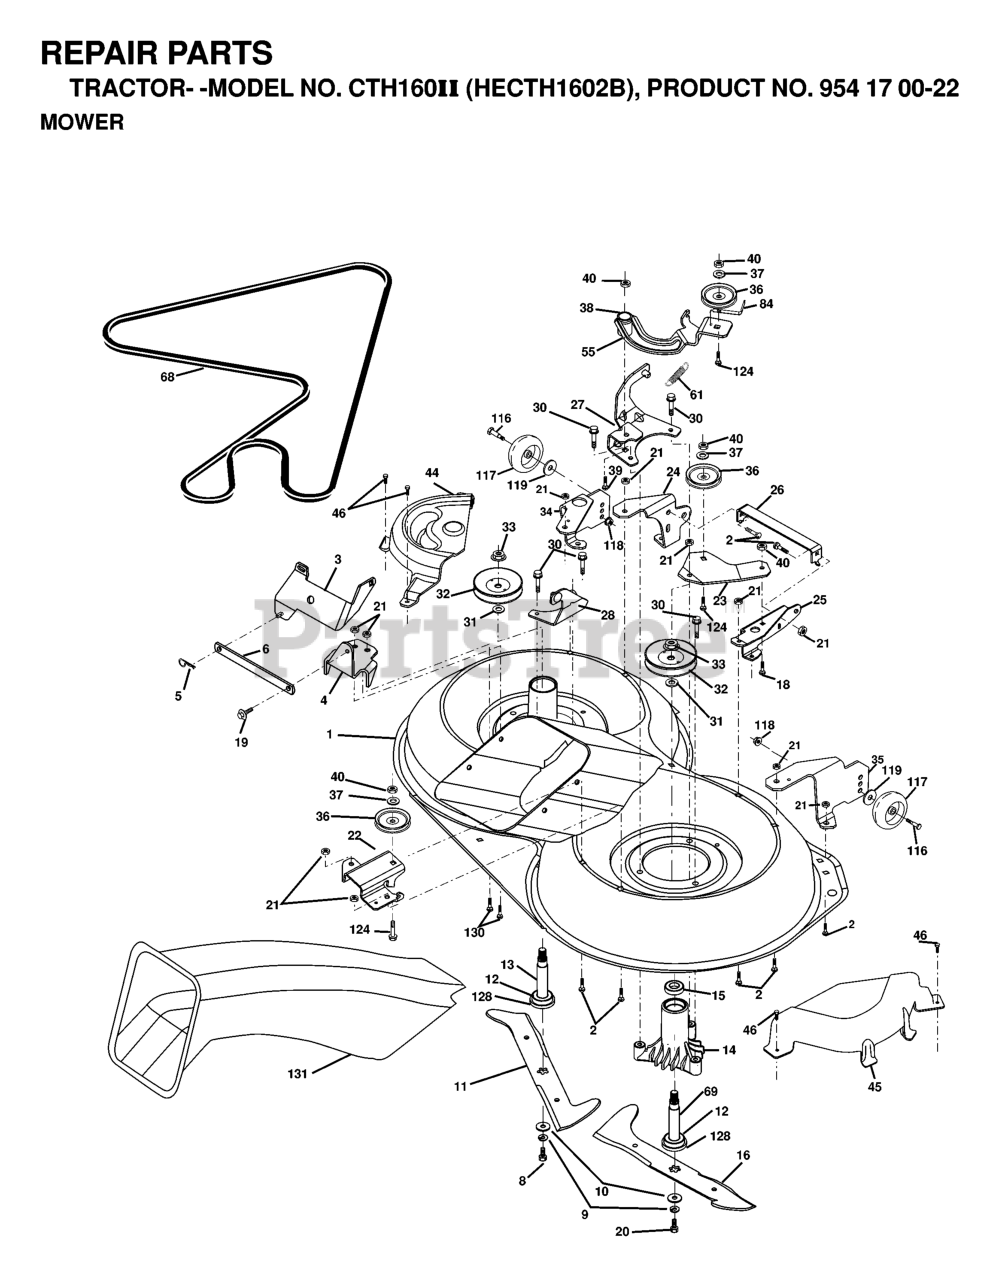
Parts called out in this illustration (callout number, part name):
1	Housing Asm. Mower 107 CRD
2	RP BOLT 5/16-18 X3/4 ZN/YEL GR
5	RETAINER-SPRNG RB
6	BAR.SWAY.92.CRD
8	BLADE BOLT
9	LOCKWASHER
10	WASHER.BLADE
11	BLADE - LH (CTH150)
12	BEARING.BALL.#6204.(MANDREL)
13	SHAFT ASM VENT
14	HOUSING.MANDREL.VENTED (MACHD)
16	BLADE - RH (CTH150)
18	BOLT D
19	BOLT SHD 5/16-18
21	LOCKNUT
22	BRACKET.IDLER.RR.107.CRD
25	BRACKET.SUSPENSION.RF.107.CRD
26	BRACE.SUPT.SUSP.FRT.CRD
28	BRACKET
30	SCREW THDROL ROLLING WASHER HD
31	WASHER
32	PULLEY/MANDREL
33	NUT
34	BRACKET
36	PULLEY.IDLER.4.25
37	WASHER
44	Cover Mandrel Lh 107 CRD
45	MANDREL COVER RH
46	SCREW.1/4-20X5/8
55	ARM.IDLER.107.CRD
61	SPRING.TENSION.BELT
68	HEX-BELT 107 MOWER
69	SHAFT.ASM.W/LWR.BRG.RH.THREAD
84	KEEPER, BELT IDLER
116	BOLT, SHOULDER
117	WHEEL GAGE DONUT
118	LOCKNUT
119	WASHER.5/16.FLAT.STE.STD.
124	BOLT.3/8-16X1.50
128	WASHER FELT
130	BOLT.CARR.SQNK.5/16-18UNC.X3/4
131	CHUTE BAGGER
